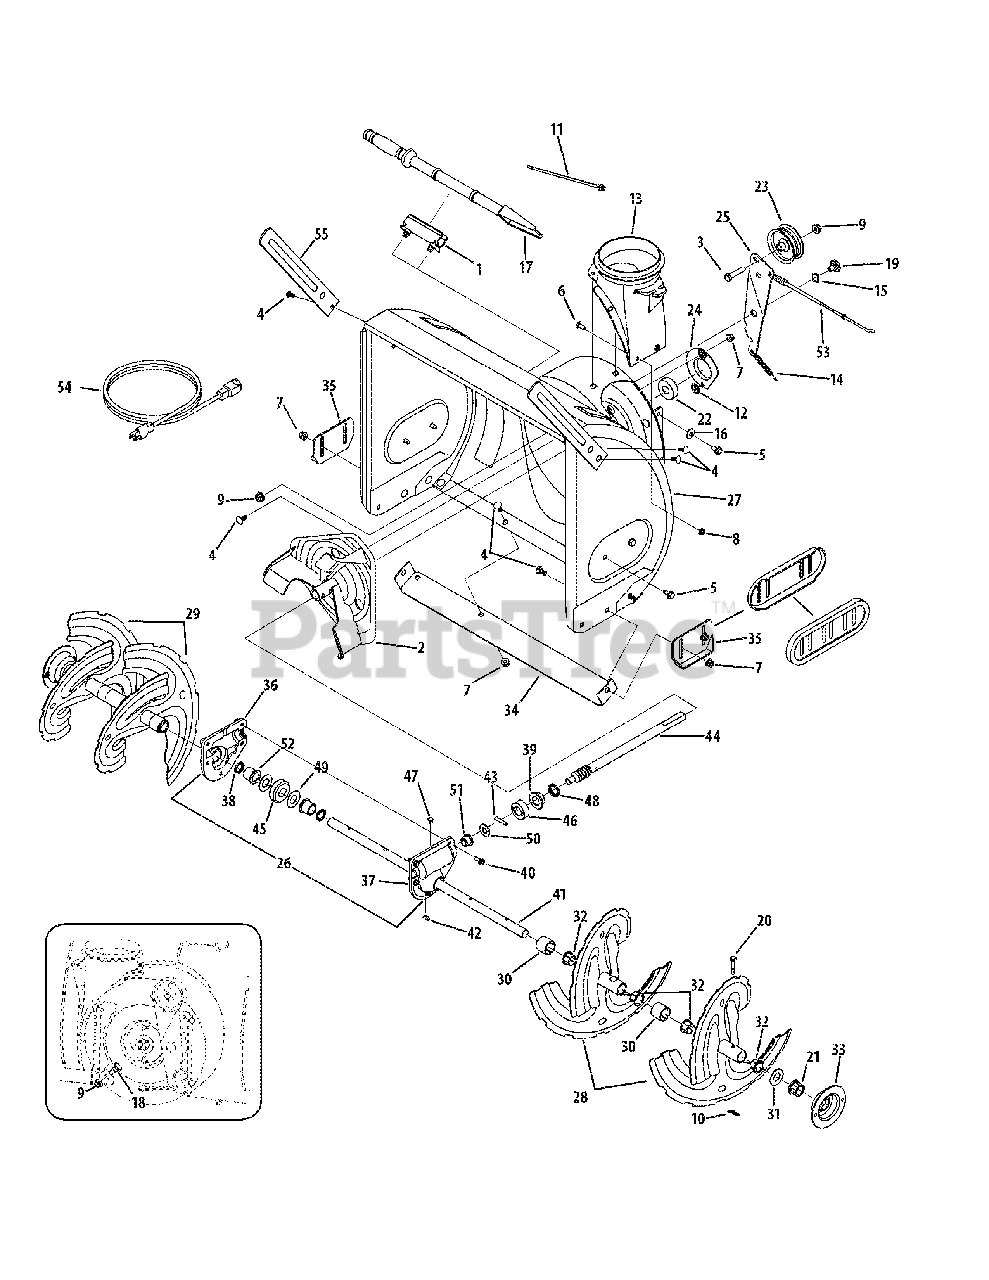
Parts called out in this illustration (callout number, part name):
1	Snow Removal Tool Mount
2	Impeller Assembly, 12''
3	Hex, Screw,3/8-16, 1.75
4	Carriage Bolt, 5/16-18, .750
5	Screw, 5/16-18, 0.750
6	Carriage Screw, 1/4-20, .750
7	Flange Lock Nut, 5/16-18, Nylon
8	Flange Lock Nut, 1/4-20, Nylon
9	Flange Lock Nut,3/8-16, Nylon
10	Bow-Tie Cotter Pin
11	Cable Tie, 3/16 x .05 x 7.4
12	Push-On Nut, .25
13	Chute Adapter, 5''
14	Extension Spring, .38 OD x 4.59
15	Wave Washer, .625 x .885 x .015
16	Bell Washer, .340 x .872 x .060
17	Snow Removal Tool
18	Shoulder Screw, .498 x .34, 3/8-16
19	Shoulder Screw, .625 x .17, 3/8-16
20	Shear Pin, .25 x 1.50
21	Hex Flange Bearing
22	Ball Bearing, .75 ID x 1.85 OD
23	Idler Flat Pulley, 2.75 OD
24	Bearing Housing, 1.85 ID
26	Auger Gearbox Assembly, 26''
30	Spacer, 1.25 OD x .75 ID x 1.00
31	Flat Washer, .76 x 1.49 x .06
32	Flange Bushing, .80 ID x .91 OD
35	Skid Shoe, Plastic
35	Skid Shoe, Stainless
35	Bolt, Carriage 5/16-18 x .750 (SS) Use w/ 790-00141
35	Screw, Carriage 5/16-18 x 1.00 (SS) Use w/ 790-00141
35	Washer, Bell .340 x 782x .060 (SS) Use w/ 790-00141
35	Nut, Hex 5/16-18 (SS) Use w/ 790-00141
36	Auger Housing, RH Reduced
37	Auger Housing, LH Reduced
38	Oil Seal, .75 x 1.131 x 1.88
39	Flange Bearing, .75 x 1.0 x .59
40	Self-tapping Screw, 1/4-20, 0.750
41	Auger Axle, 26''
42	Hi-Pro Key, 3/16 x 5/8
43	Dowel Pin, .25 OD x 1.2
44	Worm Shaft, .75 OD
45	Worm Gear, 20T
46	Thurst Collar
47	Plug, 1/4 x .437
48	Oil Seal, .75 x 1 x.131
49	Flat Washer, .760 ID x 1.5 OD
50	Flat Washer, .51 x 1.12
51	Flange Bearing, .75 x 1.0 x .925
52	Flange Bearing, .75 x 1.00 x .59
53	Auger Clutch Cable, 47.23''
54	Extension Cord, 110V, 3-prong
